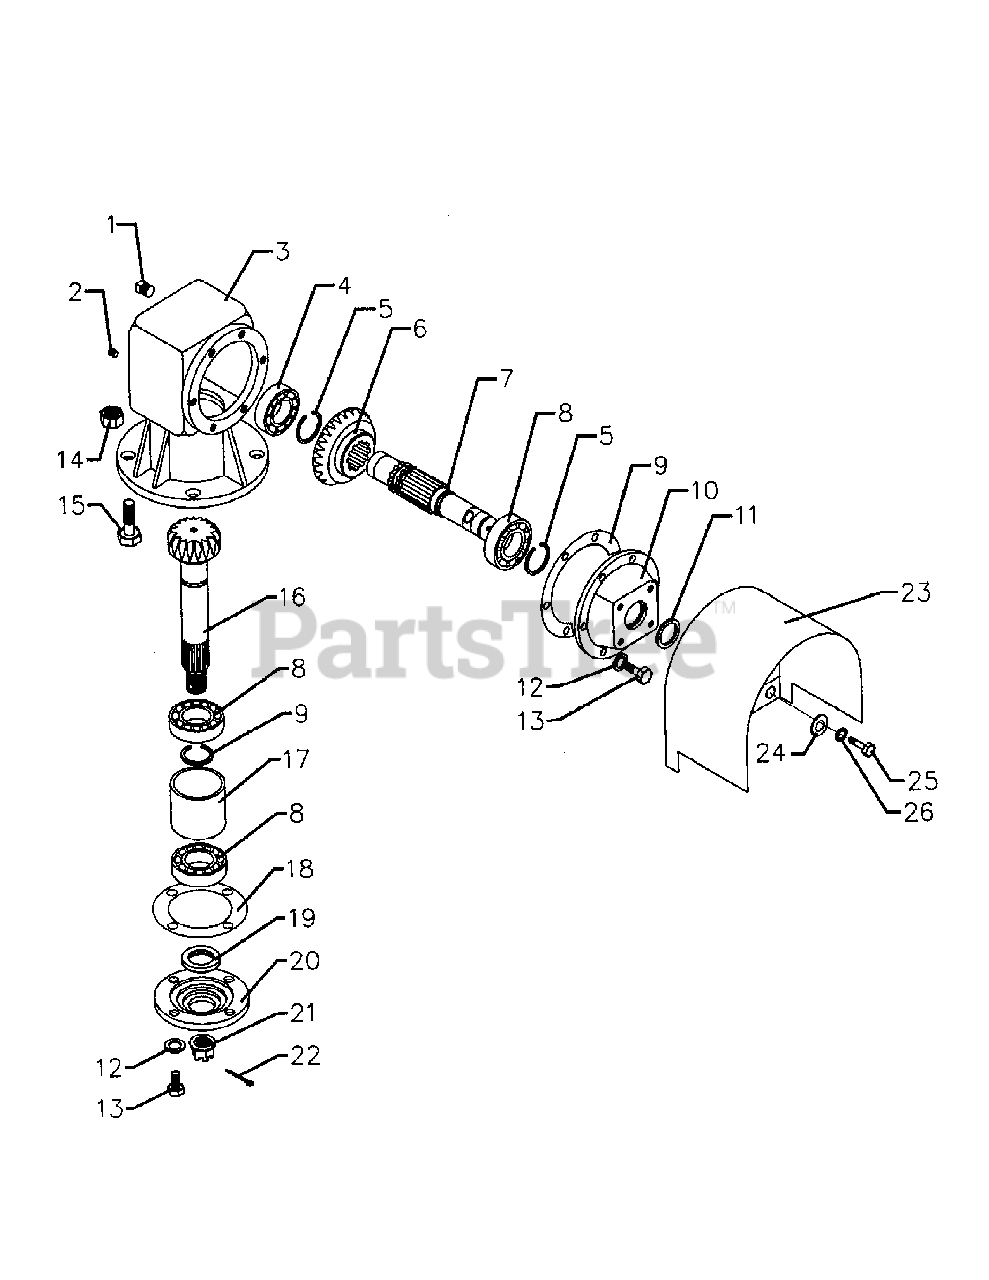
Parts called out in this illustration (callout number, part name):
1	Fill plug
2	Check plug
3	Gearbox housing
4	Bearing 6207
5	Outer snap ring
6	Ring gear (RC60 & RC72)
7	Input shaft
8	Bearing 6208
9	Shim
10	Gearbox cover
11	Oil seal
12	Lock washer Ø10
13	Cap screw 3/8"-16x1"
14	Stover nut M16
15	Bolt M16x55
16	Pinion gear (RC60 & RC72)
17	Spacer
18	Shim
19	Oil seal
20	Output cover
21	Castle nut
22	Cotter pin
23	Slip clutch shielding complete (on models w/slip clutch only)
24	Flat washer Ø8 (on models w/slip clutch only)
25	Bolt M8x20 (on models w/slip clutch only)
26	Lock washer Ø8 (on models w/slip clutch only)
